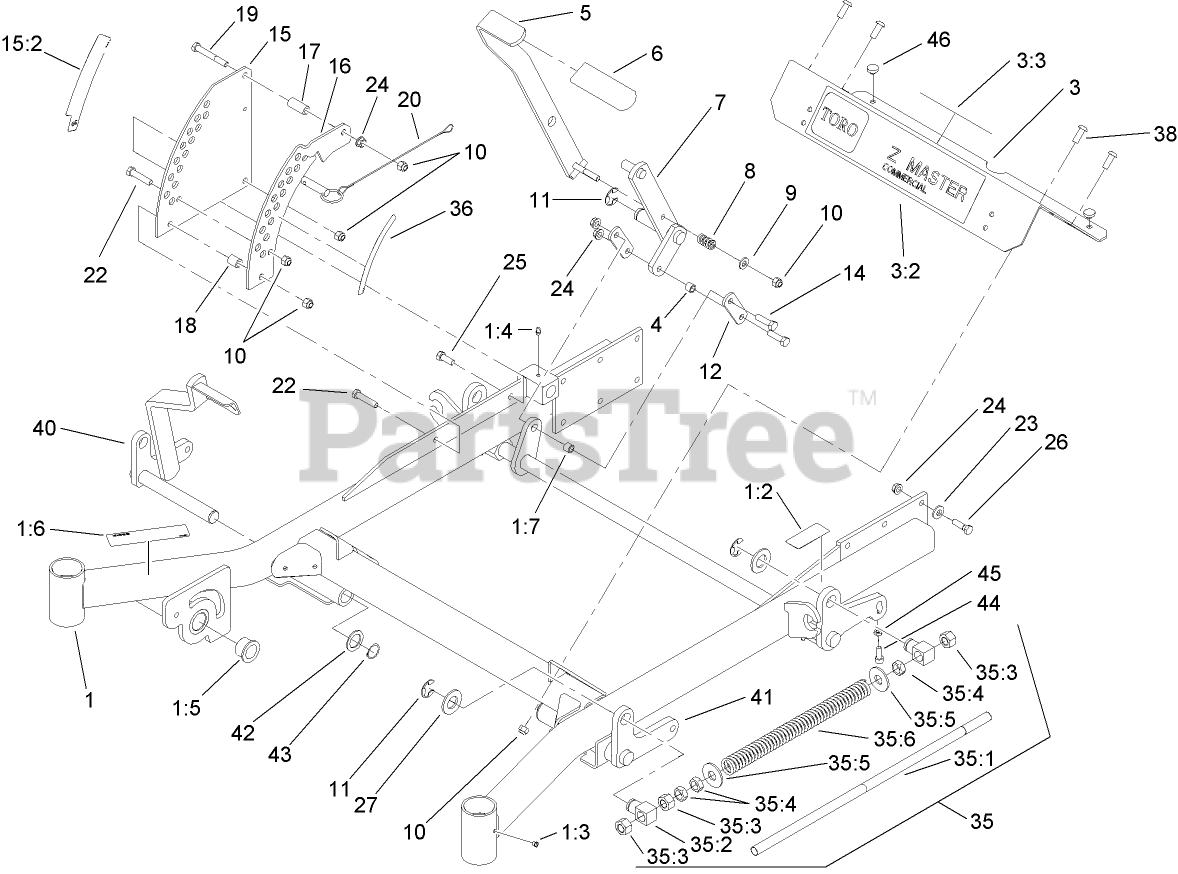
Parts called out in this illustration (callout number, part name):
1	Frame ASM
1:2	Decal-Brake, Parking
1:4	FITTING-GREASE
1:5	BUSHING
1:6	DECAL-WARNING
1:7	Bushing
3	FOOTREST
3:3	DECAL-WARNING
4	Bushing
5	LEVER-LIFT
6	GRIP-LEVER, LIFT
7	ARM-LIFT, DECK
8	SPRING-COMPRESSION
9	WASHER-FLAT
10	NUT-LOCK, NI
11	RING-RETAINING, EXT
12	ARM-LIFT, DECK
14	SCREW-HH
15	PLATE-DECK LIFT, OUTER
15:2	Decal-Height, Deck
16	PLATE-LIFT, DECK
17	BUSHING-LEVER, LIFT
18	BUSHING-LEVER, LIFT
19	SCREW-HH
20	Hitch Pin ASM
22	SCREW-HH
23	WASHER-BELLEVILLE
24	NUT-HHF, WHIZ
25	SCREW-HH
26	SCREW-HH
27	WASHER-FLAT
35	Front Frame Spring ASM
35:1	ROD-LIFT, DECK
35:2	SWIVEL-DECK MOUNT, REAR
35:3	NUT-HEX
35:4	NUT-JAM
35:5	WASHER-FLAT
35:6	SPRING-SUPPORT, DECK
36	Decal-Height, Deck
38	SCREW-HSBH
40	LIFT-DECK, RH FRONT
41	LIFT-DECK, LH
42	WASHER-SPACER
43	RING-RETAINING
44	SCREW-HSH
45	NUT-JAM
46	BUMPER
